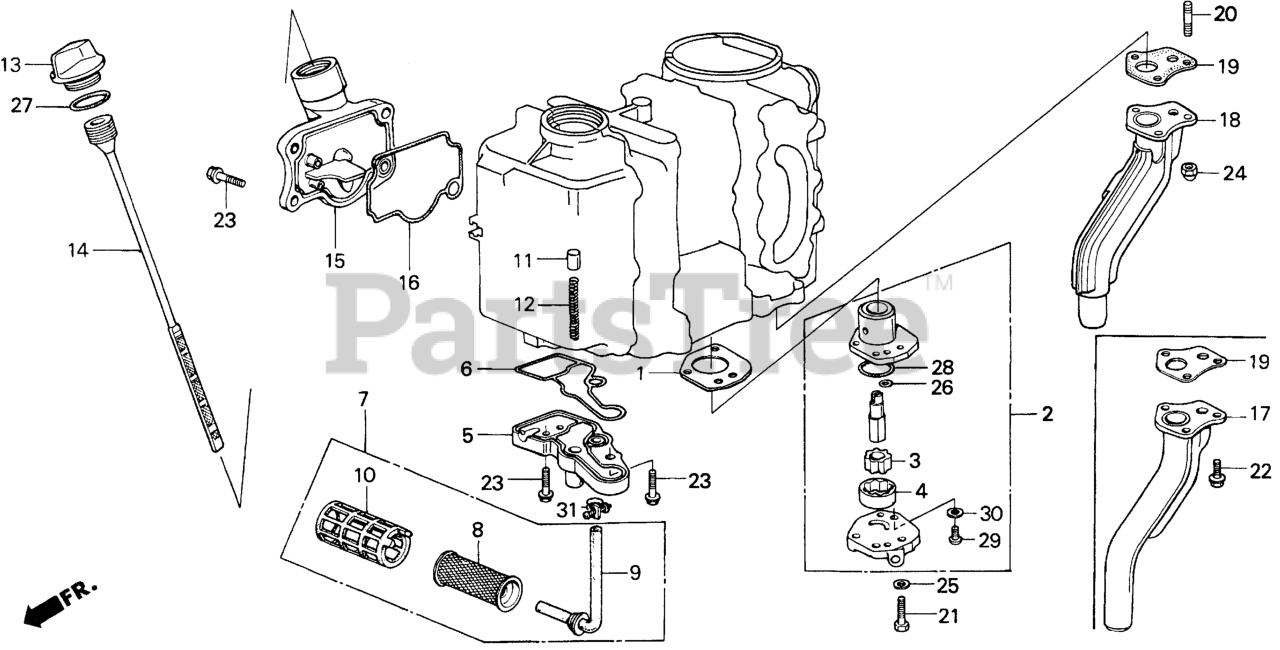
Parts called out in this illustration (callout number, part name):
1	GASKET, PUMP BODY
2	PUMP ASSY., OIL
3	ROTOR, OIL PUMP (INNER)
4	ROTOR, OIL PUMP (OUTER)
5	FLANGE, OIL FILTER
6	GASKET, OIL FILTER
7	FILTER ASSY., OIL (NOT AVAILABLE)
8	FILTER, OIL
9	TUBE, OIL (NOT AVAILABLE)
10	HOLDER, OIL FILTER
11	VALVE, CHECK
12	SPRING, VALVE
13	CAP, OIL
14	DIPSTICK, OIL
15	BODY, OIL FILLER
16	GASKET, OIL FILLER BODY
17	PIPE, EX.
19	GASKET, EX. PIPE
19	GASKET, EX. PIPE Use from Engine SN 1204900.
21	BOLT, HEX. (6X28)
22	BOLT, FLANGE (6X16)
23	BOLT, FLANGE (6X22)
25	WASHER A (6MM)
26	O-RING (6.8X1.9)
27	O-RING (26X2.7)
28	O-RING (25X1.0)
29	SCREW, PAN (5X10)
30	WASHER, PLAIN (5MM)
31	CLIP, TUBE (A12)
